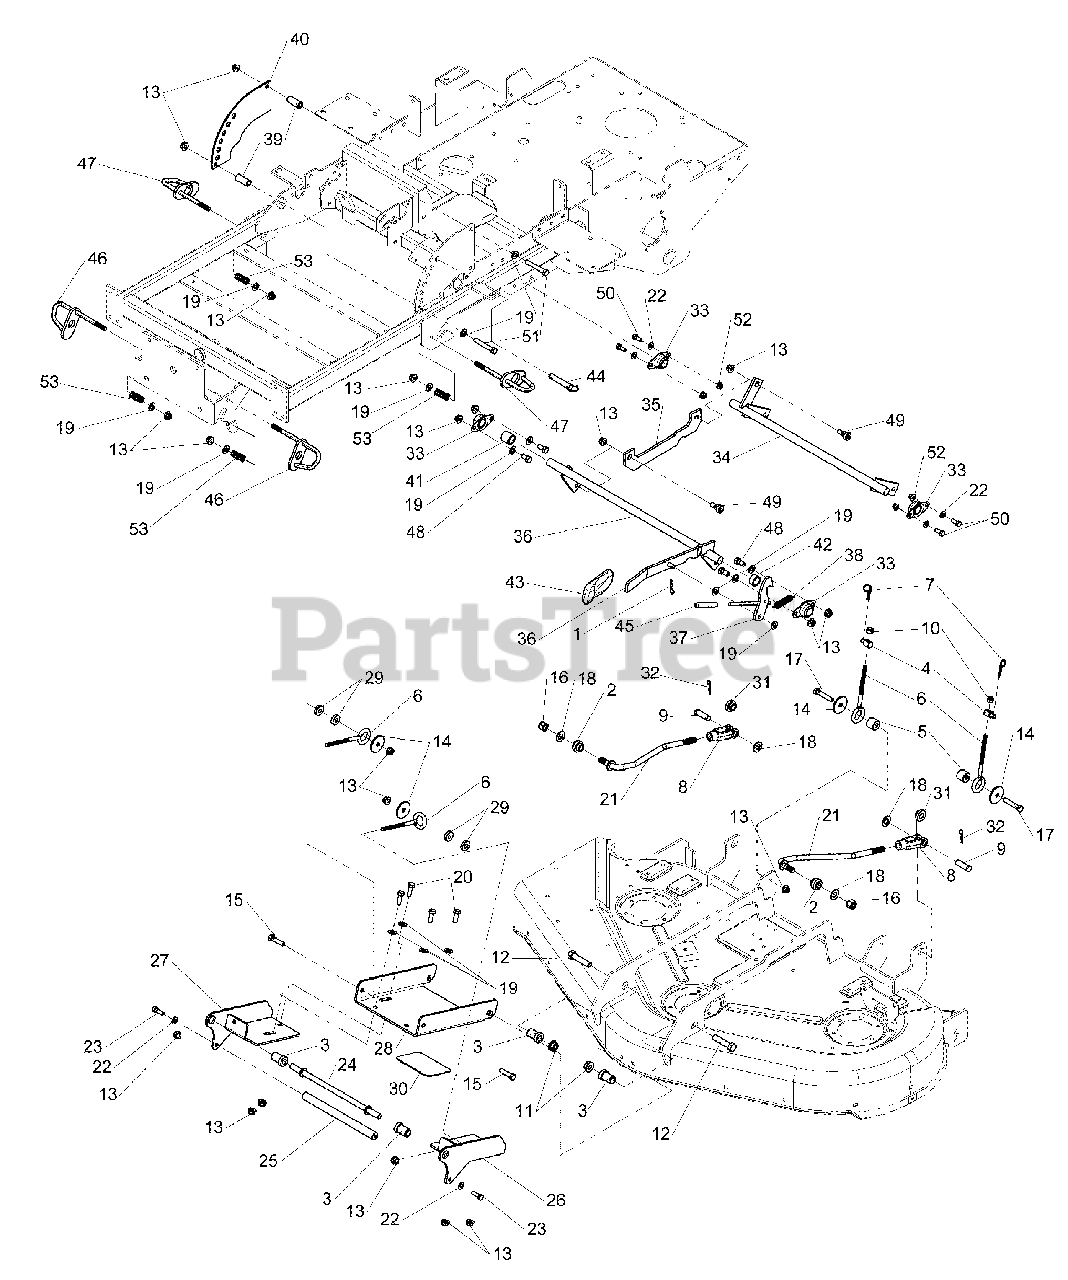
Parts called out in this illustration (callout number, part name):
1	PIN, Cotter, 3/16 X 1-1/2
2	BUSHING, REAR QUICK TACH
3	SPACER, .53 X 1.00 X 1.44
4	ADJUSTER, BRAKE LINKAGE
5	SPACER, .39 X 1.00 X .88
6	EYE BOLT, 3/8-16 X 6, 3.0 THRD, 1 EYE
7	3/32 X 1-5/8 HAIR PIN CLIP N/A
8	CLEVIS , 1/2-20, STEEL
9	PIN CLEVIS 1/2" X 1-1/4"
10	NUT, 3/8-16 HEX NYLON LOCK
11	NUT, 1/2-13 HEX NYLOCK FLANGE
12	BOLT, 1/2-13 X 2-1/4" GD5
13	NUT, 3/8-16 HEX NYLOCK FLANGE
14	WASHER, .41 X 1.75 X .14
15	BOLT, 3/8-16 X 1-1/2" GD5
16	NUT, 1/2-20 HEX NYLON LOCK
17	BOLT, 3/8-16 X 2" GD5
18	WASHER, 1/2" SAE
19	WASHER 3/8" SAE
20	BOLT, 3/8-16 X 1" GD5
21	ROD, DECK LIFT, LINKAGE
22	WASHER, 5/16" SAE
23	BOLT, 5/16-18 X 1" GD5
24	SHAFT, HANGER
25	SHAFT, HANDLE, DECK SUPPORT
26	WELD, DECK HANGER, LH
27	WELD, DECK HANGER, RH
28	PLATE, DECK HANGER SUPPORT
29	SPACER, .39 X 1.00 X .25
30	SAFETY WALK, 4.50 X 3.50
31	BUSHING, DECK SUPPORT
32	HAIRPIN
33	BEARING, BRONZE FLANGE 3/4"
34	WELD, DECK LIFT HANGER REAR
35	LINK, DECK LIFT SHAFT
36	WELD, DECK HEIGHT SHAFT
37	WELD, DECK LOCK
38	SPRING, EXTENSION
39	SPACER, .63 X .39 X 1.50
40	PLATE, INNER DECK HEIGHT
41	SPACER, .76 X 1.00 X 1.00
42	SPACER, .76 X 1.00 X .50
43	GRIP, BLACK FLEXIBLE
44	HITCH PIN, 1/2" X 2-1/2"
45	COVER, VINYL HANDLE
46	WELD, QUICK RELEASE HANDLE, FRONT
47	WELD, QUICK RELEASE HANDLE, REAR
48	BOLT, 3/8-16 X 3/4" GD5
49	SHOULDER BOLT, 3/8-16 X 1/2 X 3/8
50	BOLT, 5/16-18 X 3/4" GRD5
51	BOLT, 3/8-16 X 2-1/2" GD5
52	NUT, 5/16-24 HEX NYLOCK FLANGE
